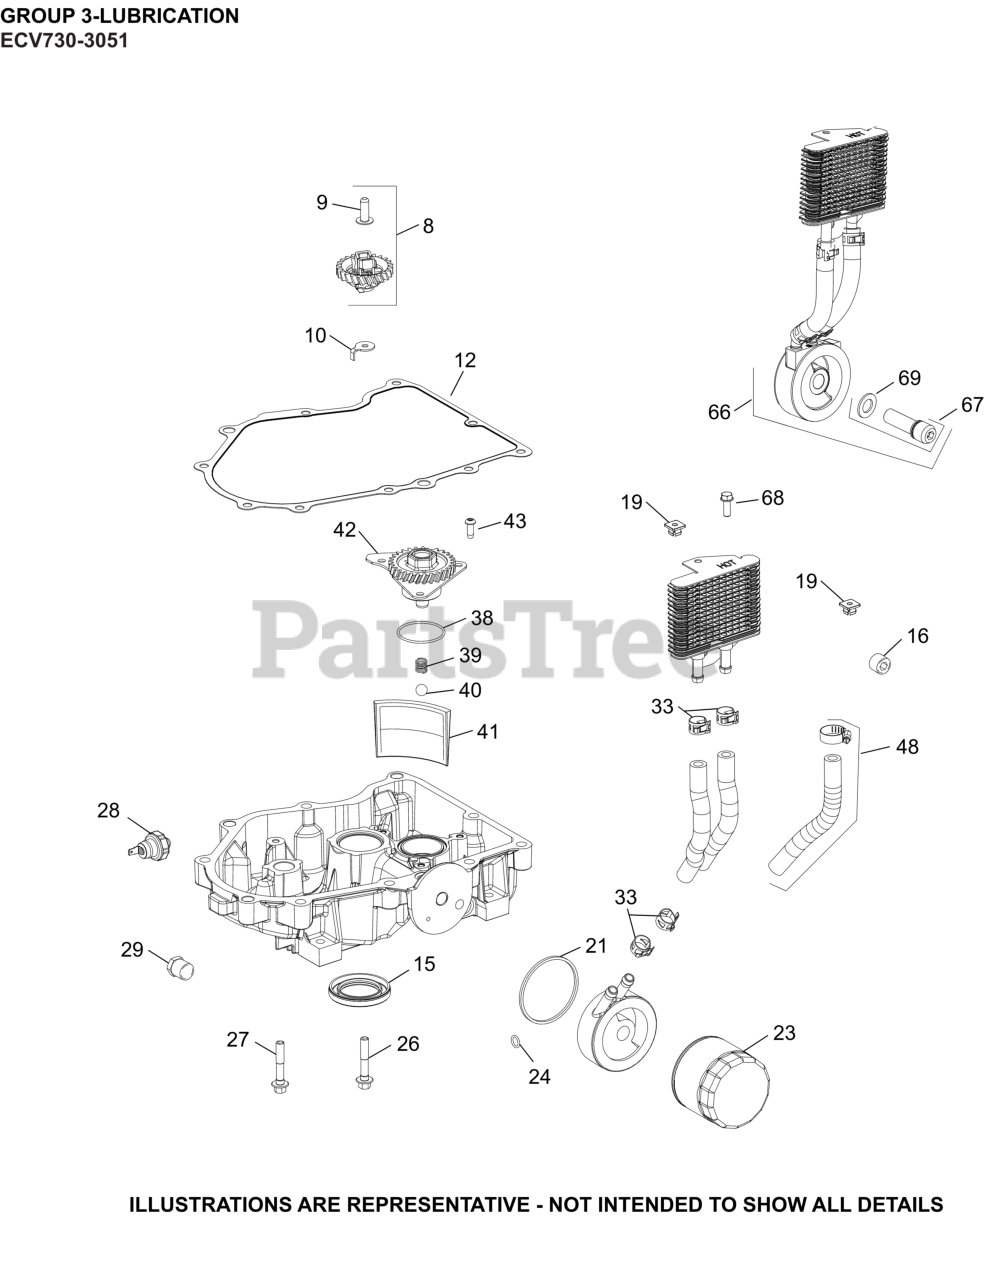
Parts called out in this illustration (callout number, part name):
8	KIT, GOVERNOR GEAR W/PIN
9	PIN, GOVERNOR REGULATING
10	TAB, LOCKING
12	KIT, OIL PAN GASKET
16	PLUG, PIPE CTSK 3/8"
19	NUT, PLASTIC - BLACK
21	O-RING, OIL COOLER
23	OIL FILTER
24	O-RING (.5" DIA)
26	SCREW, HEX FLANGE
27	SCREW, FLG M8X1.25X45
28	SWITCH, OIL PRESSURE
29	PLUG, HD PIPE 3/8"
33	CLAMP, HOSE LOW PROFILE
38	O-RING (1.78" DIA)
39	SPRING, COMPRESSION
40	PRESSURE RELIEF BALL
41	SCREEN, OIL
42	PUMP, OIL ASSEMBLY
43	SCREW, BUTTON HEAD
48	KIT, HOSE 140MM
66	KIT, OIL COOLER
67	KIT, OIL FILTER NIPPLE
68	SCREW, HEX HEAD
69	WASHER, FLAT
NI	PAN, ASSEMBLY OIL (SERVICE)
NI	SHAFT, GOVERNOR GEAR
